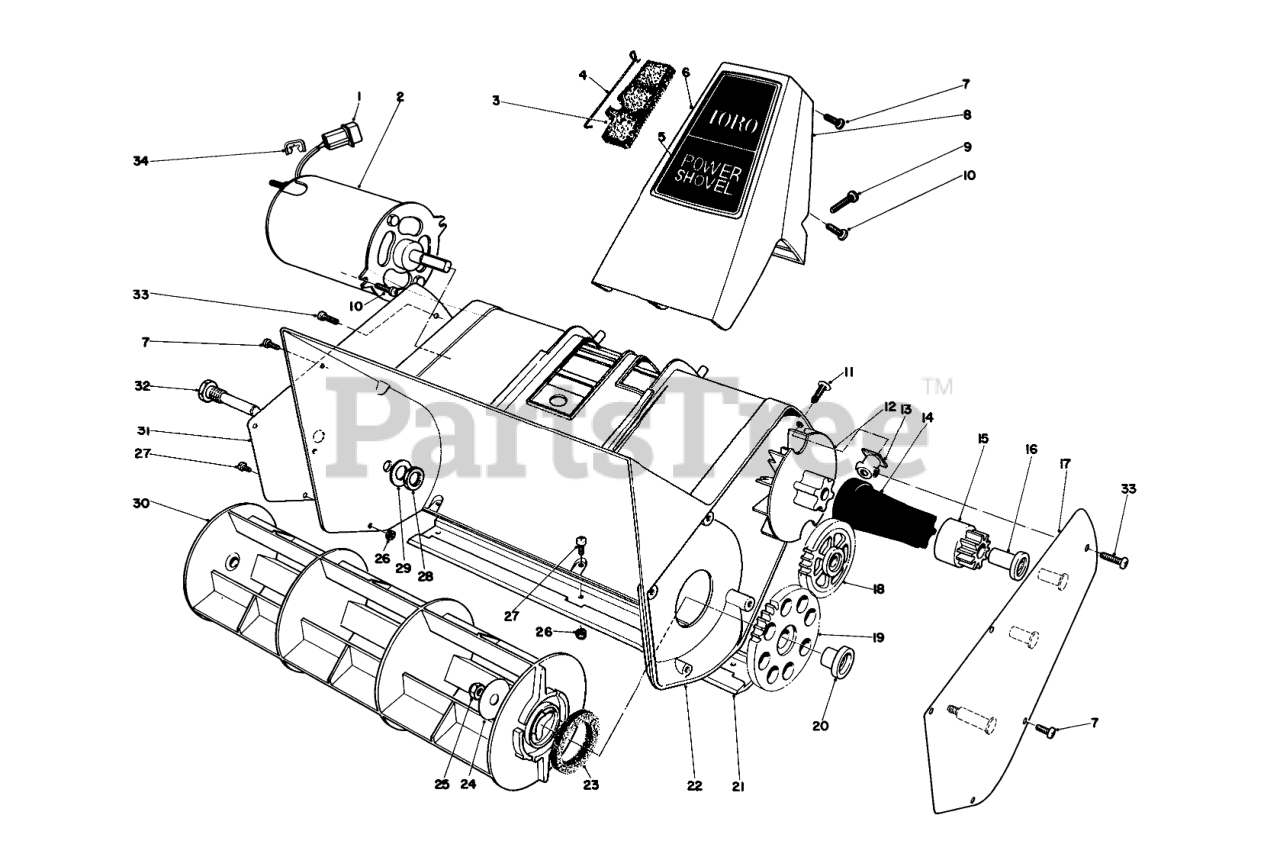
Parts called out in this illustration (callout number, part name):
1	Pin Housing
2	Motor
3	FOAM FILTER
4	RETAINER - FILTER
5	HANDLE SUPT DECAL
6	Handle Support-Front
7	SCREW-PPH
8	Handle Support-Back
9	SCREW-PPH
10	SCREW-PPH
11	XMAS TREE FASTENER
12	FAN, POWER SHOVEL
13	MTG BLOCK
14	DRIVE COUPLING
15	Drive Gear (Incl. Ref. #16)
16	BUSHING, DRIVE GEAR
17	Gear Carrier
18	Idler Gear
19	Rotor Gear Assy. (Incl. Ref. #20)
20	BUSHING, ROTOR GEAR
21	Scraper
22	Housing
23	FELT WASHER
24	ROTOR WASHER
25	NUT-LOCK, NI
26	NUT-LOCK
27	SCREW-PPH
28	3/8 24 JAM NUT
29	WASHER-FLAT
30	ROTOR
31	RT. SIDE COVER (RAW)
32	ROTOR PIN
33	Screw
34	Strain Relief
